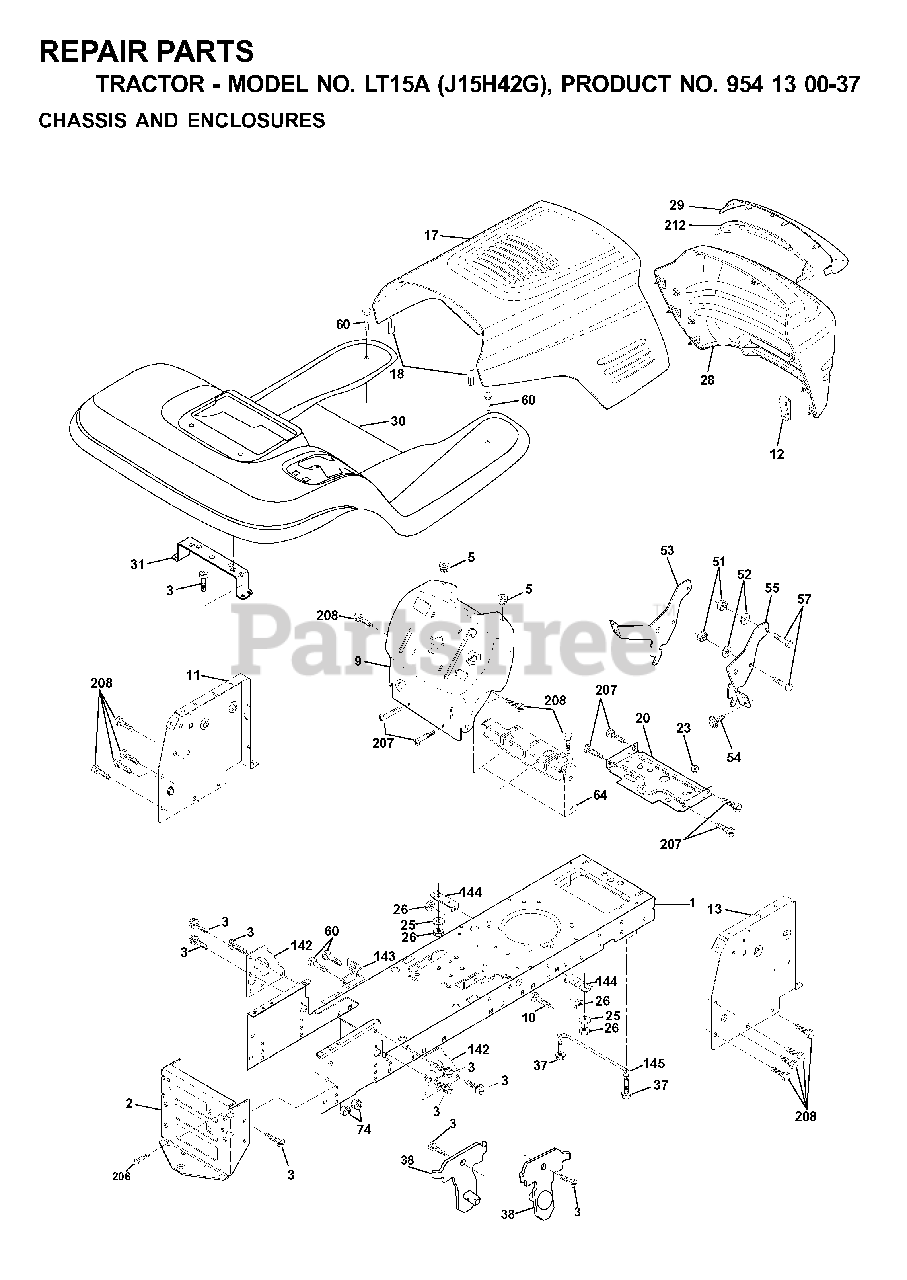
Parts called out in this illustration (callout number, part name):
2	DRAWBAR
3	SCREW 3/8-16X3/4
5	BUMPER.RUBBER.HOOD
10	BOLT D
11	PANEL DASH LH
13	PANEL DASH
14	SCREW LT
18	BUMPER HOOD T
20	PLATE MTG
23	GROMMET T
25	WASHER
26	NUT
37	SCREW LT
38	BRACKET
51	LOCKNUT
52	WASHER
57	BOLT
64	DASH LOWER
74	LOCKNUT
140	BRACKET SUSPENSION FRONT
142	PLATE
143	BRACKET, SWAY BAR
144	BRACKET FOOTREST
145	ROD PIVOT CHASSIS/HOOD
206	SHOULDER BOLT 5/16-18TT
207	SCREW, 5/16-18 X 1/2
208	SCREW 3/8-16X1/2
